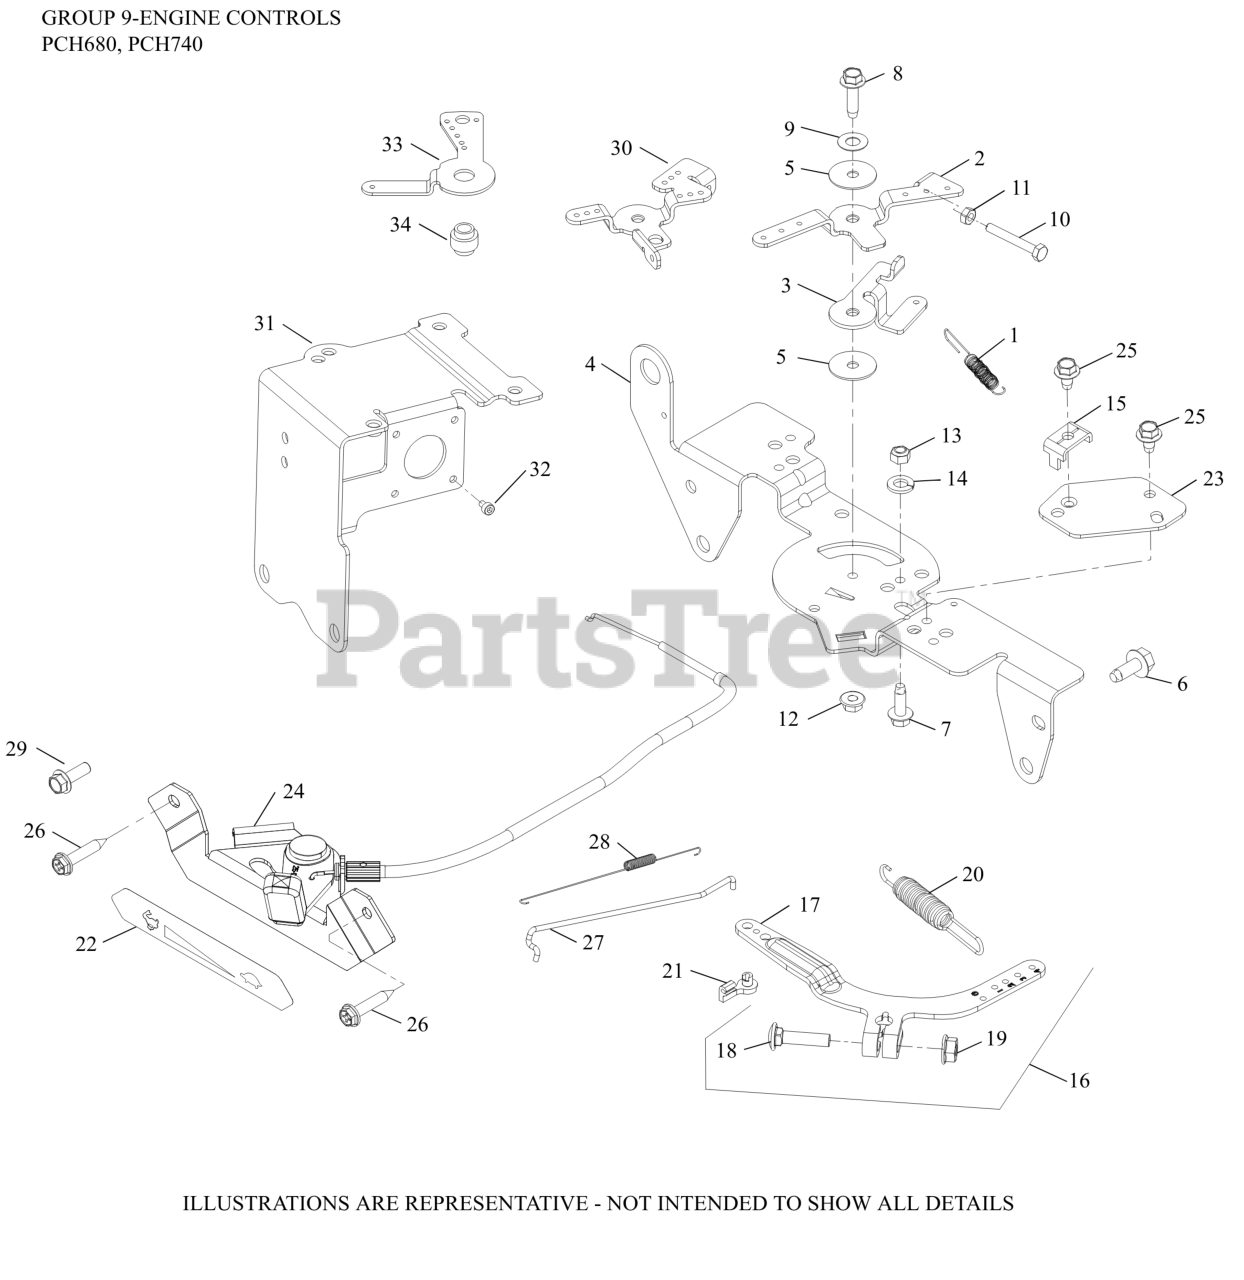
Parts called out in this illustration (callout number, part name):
1	SPRING, THROTTLE LIMITER
2	LEVER, THROTTLE CONTROL
3	LEVER, THROTTLE ACTUATOR
4	BRACKET, CONTROL
5	WASHER, FLAT 5.5 MM
6	SCREW, THREAD FORMING
7	SCREW, THREAD FORMING
8	SCREW, THD FRM-USE 25 086 473-S
9	WASHER, SPRING 1/4"
10	SCREW, CAP M4X.7X30
11	NUT, M4X0.7
12	NUT, FLG M5X.8
13	NUT, LOCK M5X.8
14	WASHER, SPRING LOCK 1/4"
15	CLAMP, CABLE-(#2523753S)
16	LEVER, GOVERNOR ASSEMBLY
17	LEVER, GOVERNOR - (#2409069S)
18	BOLT, RD HD SQ NECK M6X1.0X25
19	NUT, FLG M6X1.0
20	SPRING, GOVERNOR (BLACK)
21	BUSHING, THROTTLE LINKAGE
22	LABEL, CONTROL PANEL
23	BRACKET, CABLE SUPPORT
24	CABLE, CONTROL ASSEMBLY
25	SCREW, THREAD FORMING
27	LINKAGE, THROTTLE
28	SPRING, LINKAGE
29	SCREW, HI-LOW
